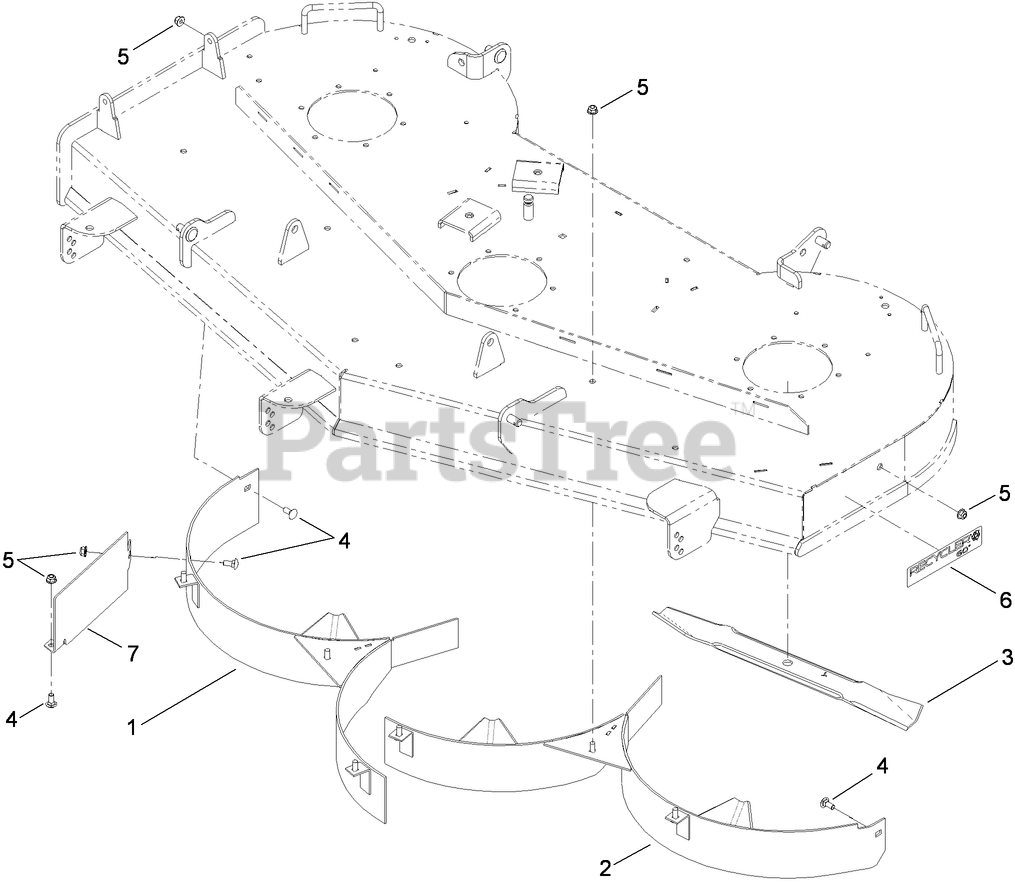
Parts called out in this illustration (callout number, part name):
1	BAFFLE-RECYCLER, RH
2	BAFFLE-RECYCLER, LH
3	BLADE-MULCH, 20.50 INCH
4	BOLT-CARR
5	NUT-HF, NI
6	DECAL-RECYCLER, 60 INCH
7	GUARD-BAFFLE
